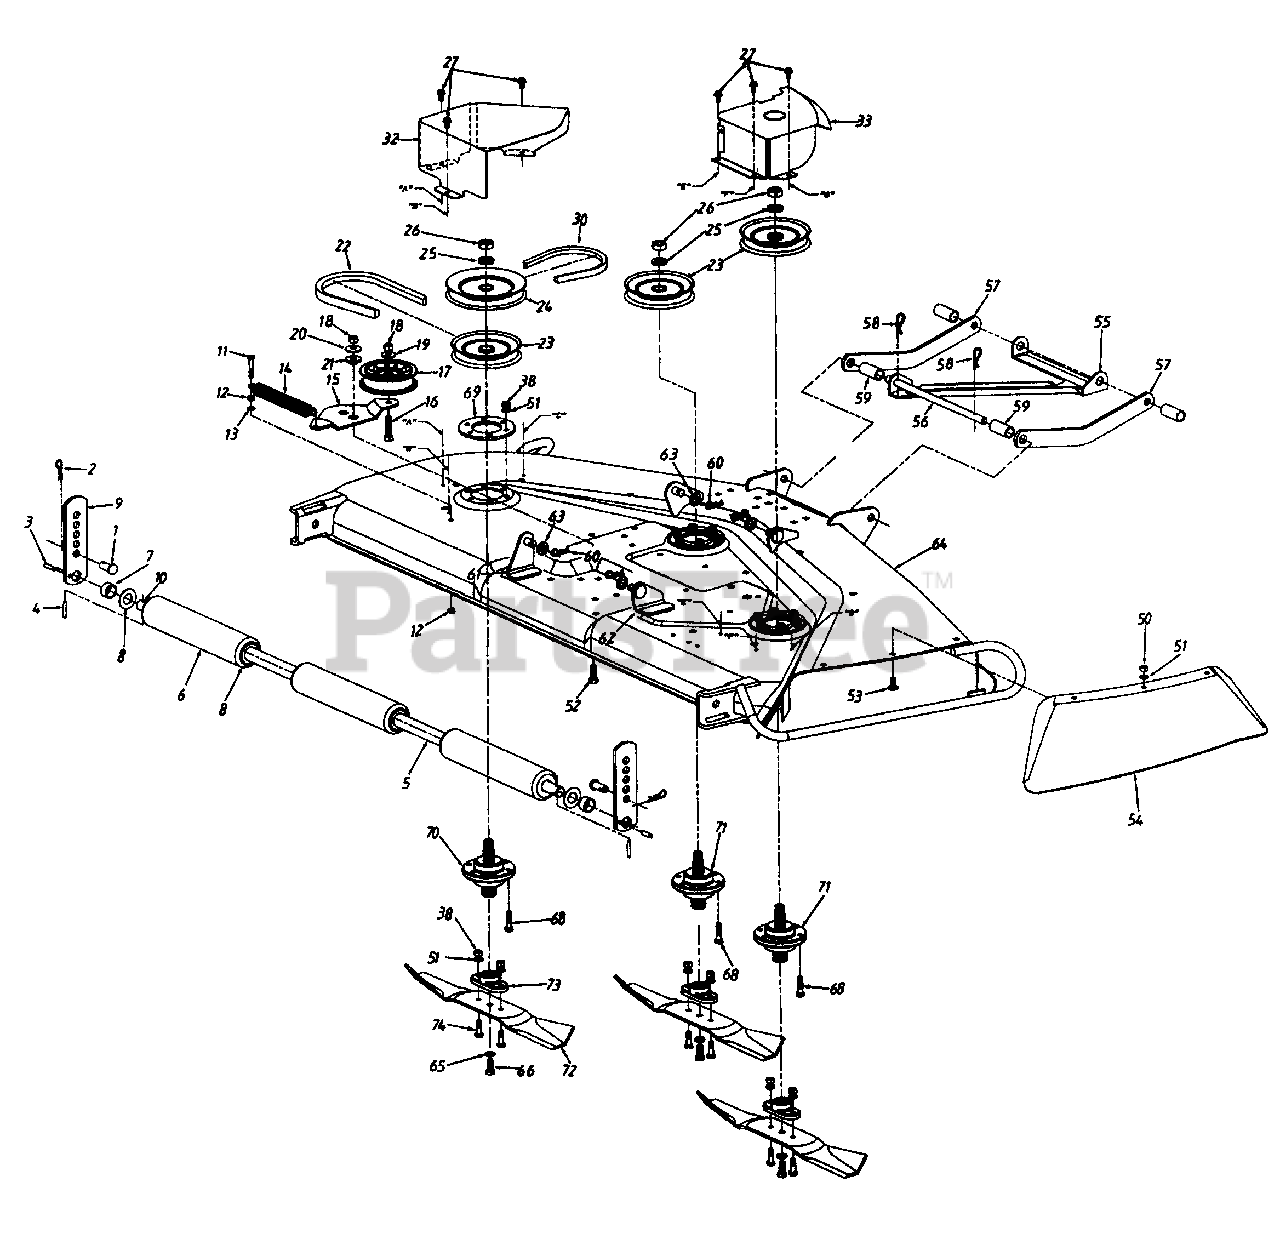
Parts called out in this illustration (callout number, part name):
1	Clevis Pin
2	Hairpin Clip
3	Spring Pin 1/4" x 1" Lg.
4	Spring Pin 3/16" x 1-1/4" Lg.
7	Spacer .75" I D.
8	Fl-Wash .76" I.D. x 1.5" O.D.
10	Roller Shaft
11	Hex Bolt 1/4-28 x 1.5" Lg. (Gr. 5)
12	Hex Nut 1/4-28 Thd.
13	L-Wash. 1/4" I.D.
14	Ext. Spring 7.33" Lg.
17	Idler Pulley
18	Hex Nut 3/8-24 Thd.
19	Bell-Wash. 3/8" I.D.
20	Bell-Wash .39" I.D. x 1.13" O.D.
21	Shld. Spacer.625" I.D.
22	"V"-Belt
23	Deck Pulley
24	Upper Deck Pulley
25	L-Wash. 5/8" I.D.
26	Hex Jam Nut 5/8-18 Thd.
27	Hex Tap Scr. 1/4-20 x .5"
30	"V"-Belt
50	Hex Nut 5/16-18 Thd.
51	L-Wash. 5/16" I.D.
52	Hex Bolt 3/8-24 x 1" Lg.
53	Carr. Bolt 5/16-18 x .75" Lg.
59	Spacer 1.75" Lg.
60	Hairpin Clip
63	Fl-Wash. 1/2" I.D. x .93" Q.D.
66	Hex Bolt 3/8-24 x .88" Lg. (Gr. 5)
68	Hex Bolt 5/16-24 x 1-1/4" Lg. (Gr. 5)
69	Spindle Reinforcement Plate
70	Spindle Ass'y. (L.H.)
71	Spindle Ass'y. (R.H. & Center)
72	Blade
73	Blade Adapter
74	Hex Bolt 5/16-24 x 1" Lg.
12649-0638	GUARD-CHUTE - MTD/TROY-BILT RED (0638)
12649-0648	GUARD-CHUTE - TECH GRAY (0648)
12650-4008	Height Adjuster - WINE RED (4008)
